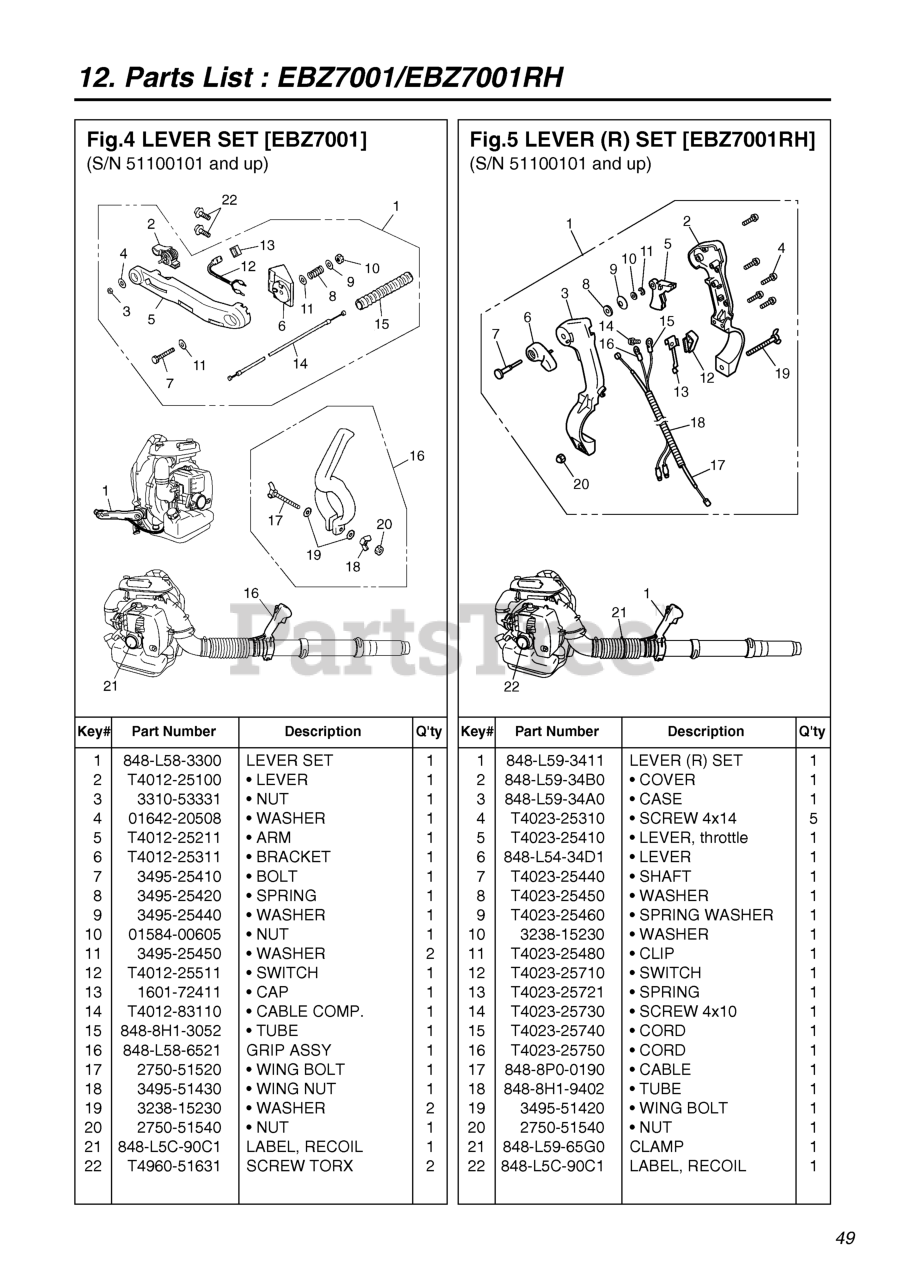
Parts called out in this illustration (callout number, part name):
1	LEVER (R) SET
2	COVER
3	CASE
4	SCREW 4X14
5	LEVER, THROTTLE
6	LEVER
7	SHAFT
8	WASHER
9	SPRING WASHER
10	WASHER
11	CLIP
12	SWITCH
13	SPRING
14	SCREW 4X10
15	CORD
16	CORD
17	CABLE
18	TUBE
19	BOLT, WING
20	NUT
21	CLAMP
22	LABEL, RECOIL
